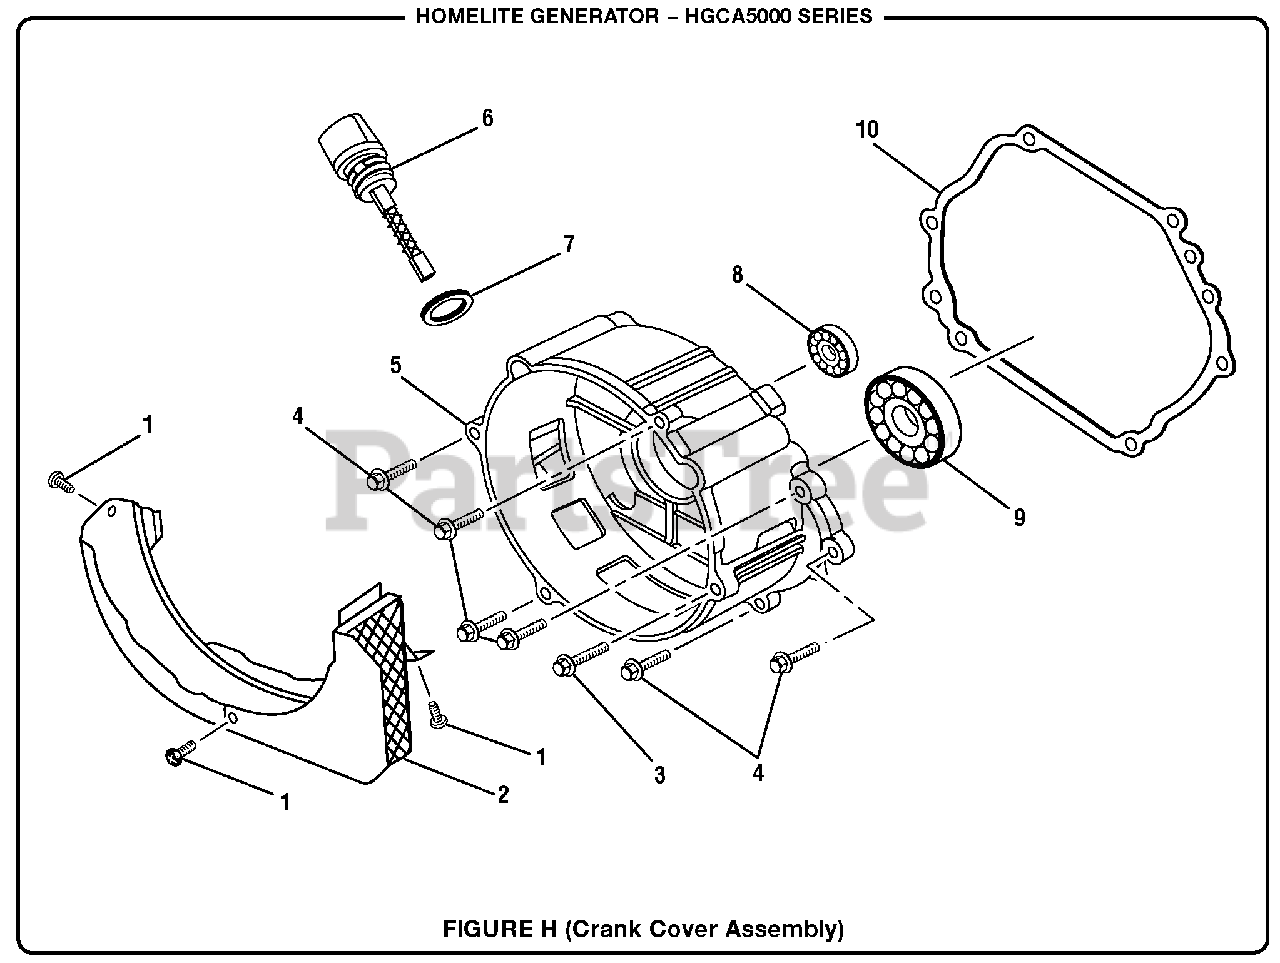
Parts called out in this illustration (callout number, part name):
1	Bolt (M5 x 12 mm, Flange Hd.)
2	Guard Cover (Crankcase)
3	Bolt (M8 X 40 mm)
4	Bolt (M8 X 35 mm)
5	Crankcase Cover Assembly .
6	Dipstick Assembly (Incl. Key No. 7)
7	Gasket (Dipstick)
8	Ball Bearing (6202)
9	Ball Bearing 6207
10	Gasket (Crankcase)
